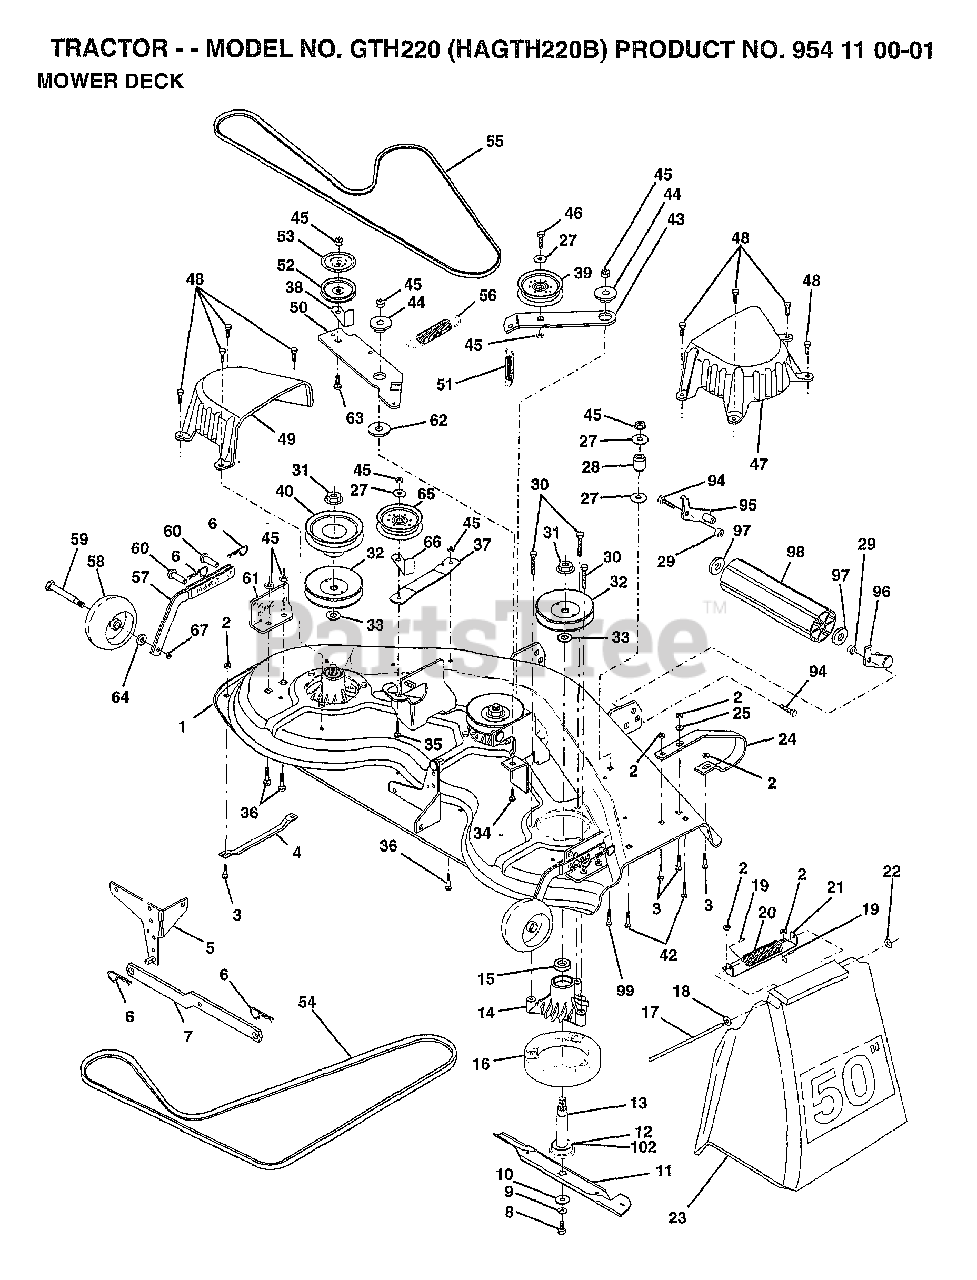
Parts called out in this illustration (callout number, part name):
2	LOCKNUT, CROWN 5/16-18
3	BOLT, CARRIAGE 5/16-18 X 3/4
9	WASHER LOCK HVY 3/8
18	WASHER 11/32 X 5/8 X 16 GA
25	WASHER 11/32 X 3/4 X 16 GA
27	WASHER 13/32 X 13/16 X 16 GA
28	IDLER SPRG SPACER
29	LOCKNUT
34	BOLT, CARRIAGE 3/8-16 X 1-1/4
35	BOLT, CARRIAGE 3/8-16 X 2
36	BOLT, CARRIAGE 3/8-16 X 1
42	BOLT, CARRIAGE
45	NUT, CROWNLOCK 3/8-16
46	BOLT, FIN HEX 3/8-16 UNC X 1-3/4
63	BOLT, CARRIAGE 3/8-16 X 1-1/2 GR.5
64	WASHER 3/8 X 7/8 X 14 GA.
67	NUT, CENTER LOCK 3/8-16
94	BOLT FIN HEX 3/8-16 X 1
95	BRK ASM ROLLER LH
96	BRK ASM ROLLER RH
97	WASHER, 17/32 X 7/8 X 16 GA.
99	BOLT
